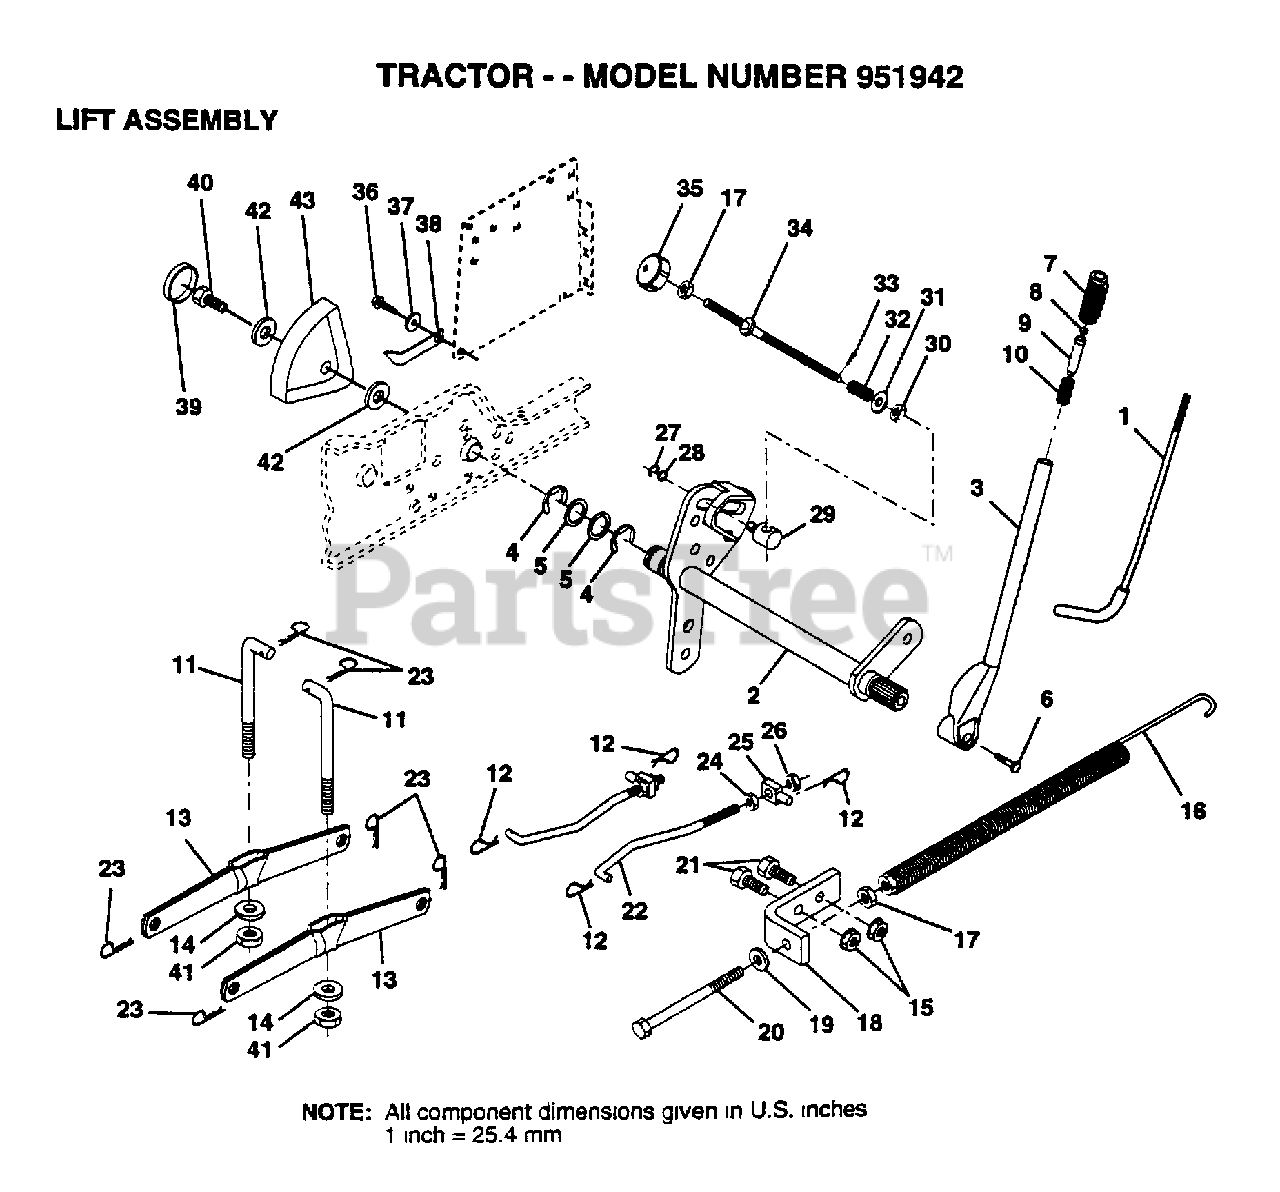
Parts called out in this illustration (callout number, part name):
1	LEVER ROD LT
2	SHAFT.LIFT.VGT.95
4	E-RING
5	WASHER
6	"BOLT,HEX"
7	GRIP HANDLE
10	SPRING T
11	LINK.LIFT.MWR.VGT
12	RETAINER.SPRING
13	ARM SUSP REAR
14	BEARING PVT LH
17	NUT
18	BRACKET SPRING AS
19	WASHER
20	BOLT-ADJ SPRING T
21	BOLT
22	LINK.FRONT
24	NUT
25	TRUNION
26	NUT.LK.W/WSH.1/2.
27	KLIP RING
28	WASHER
29	TRUNION LT
30	NUT T
31	WASHER
32	SPRING.COMP.INF.H
34	ROD.ADJ.LIFT
35	KNOB INF 3/8-16
36	SCREW
37	WASHER T
38	POINTER HGT IND
39	"PLUG,HOLE"
40	SCREW
41	NUT
42	WASHER
43	HEIGHT INDICATOR
